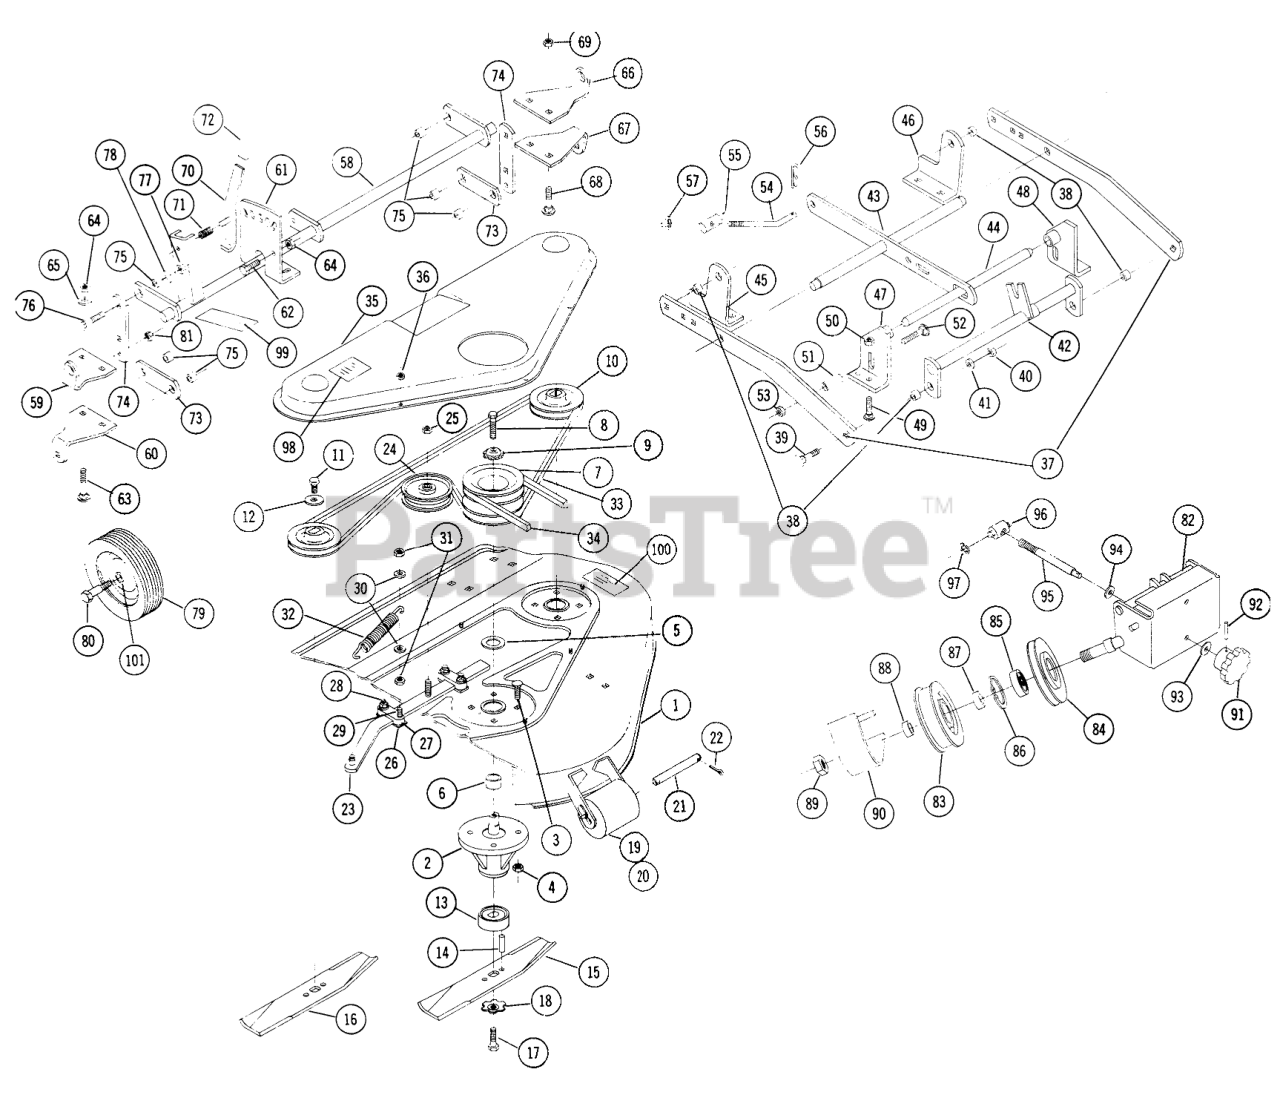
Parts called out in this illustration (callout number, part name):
1	Deck-Mower-Rear Discharge 5-0622)
1	Deck-Mower Side Discharge (5-0720)
2	Assy.-Sealed Spindle Bearing
3	Bolt Carriage 3/8-16 x 1
5	WASHER
6	SPACER-PULLEY
7	Pulley-Center-Drive
8	Bolt 3/8-16 x 7/8
9	WASHER
10	Pulley-End
11	Bolt 3/8-16 x 3/4 Hex
12	WASHER
13	Cup-Spindle
14	SPIROL ROLL PIN
15	Blade 14"
15	Blade 14" (5-0710 & 5-0711)
16	Blade 12"
16	Blade 12" (5-0710 & 5-0711)
17	Bolt 3/8-16 x 7/8
18	WASHER
19	Roller
20	BUSHING
21	CLEVIS PIN
22	Cotter Pin
23	Bar Idler Support
24	Idler Pulley
25	3/8-16 Jam Nut
26	SLIDE
27	Side Block
28	Bolt-5/16-18 x 1/4
29	Bolt-5/16-18 x 1 1/2
30	Washer
31	Nut-Nylok
32	SPRING R
33	V-BELT
34	V-BELT
35	Cover
36	HEX NUT 10-32 E.S.
37	Bar Draft
38	SPACER
39	Bolt-3/8-16 x 1
41	Washer
42	Hitch
43	Leveler-Assy.
44	Front Shaft
45	R.H. Rear Bracket
46	L.H. Rear Bracket
47	Front Bracket LH
48	Front Bracket RH
49	Bolt-3/8-16 x 3/4
51	SPACER-BEARING
52	Bolt-7/16 x 1 1/2
53	Nut, 7/16-14
54	ROD-LEVEL ADJUST
55	TRUNNION-LIFT
56	Hairpin
57	3/8-16 E.S.
58	Gage Wheel Support Assy.
59	Bracket-R.H. Upper
60	Bracket-Lower R.H.
61	Quadrant
62	Bolt 3/8-16 x 3/4
63	Bolt-Carriage 1 1/2
65	Washer
66	Bracket-L.H. Upper
67	Bracket-L.H. Lower
68	Bolt 3/8-16 x 1
70	Lever
71	SPRING-COMPRESSION
73	SUPPORT LINK R
74	WHEEL SUPPORT LINK
75	SPACER
76	Bolt-3/8-16 x 1
78	Washer
79	Wheel
80	BOLT-SHOULDER
82	Front Support
83	Pulley-Flat Idler
84	Pulley-V Idler
85	BEARING-BALL
86	INT SNAP RING
87	SPACER
88	SPACER-OUTER
89	Nut-3/4-16 E.S.
90	Belt Cover
91	KNOB-ADJUSTMENT
92	PIN-ROLL
93	Washer
94	Washer
95	ROD ADJ
96	TRUNNION-DOUBLE
97	E Ring-3/8
98	Decal-Belt Installation
99	Decal Height Adjustment
100	Decal
101	BEARING
